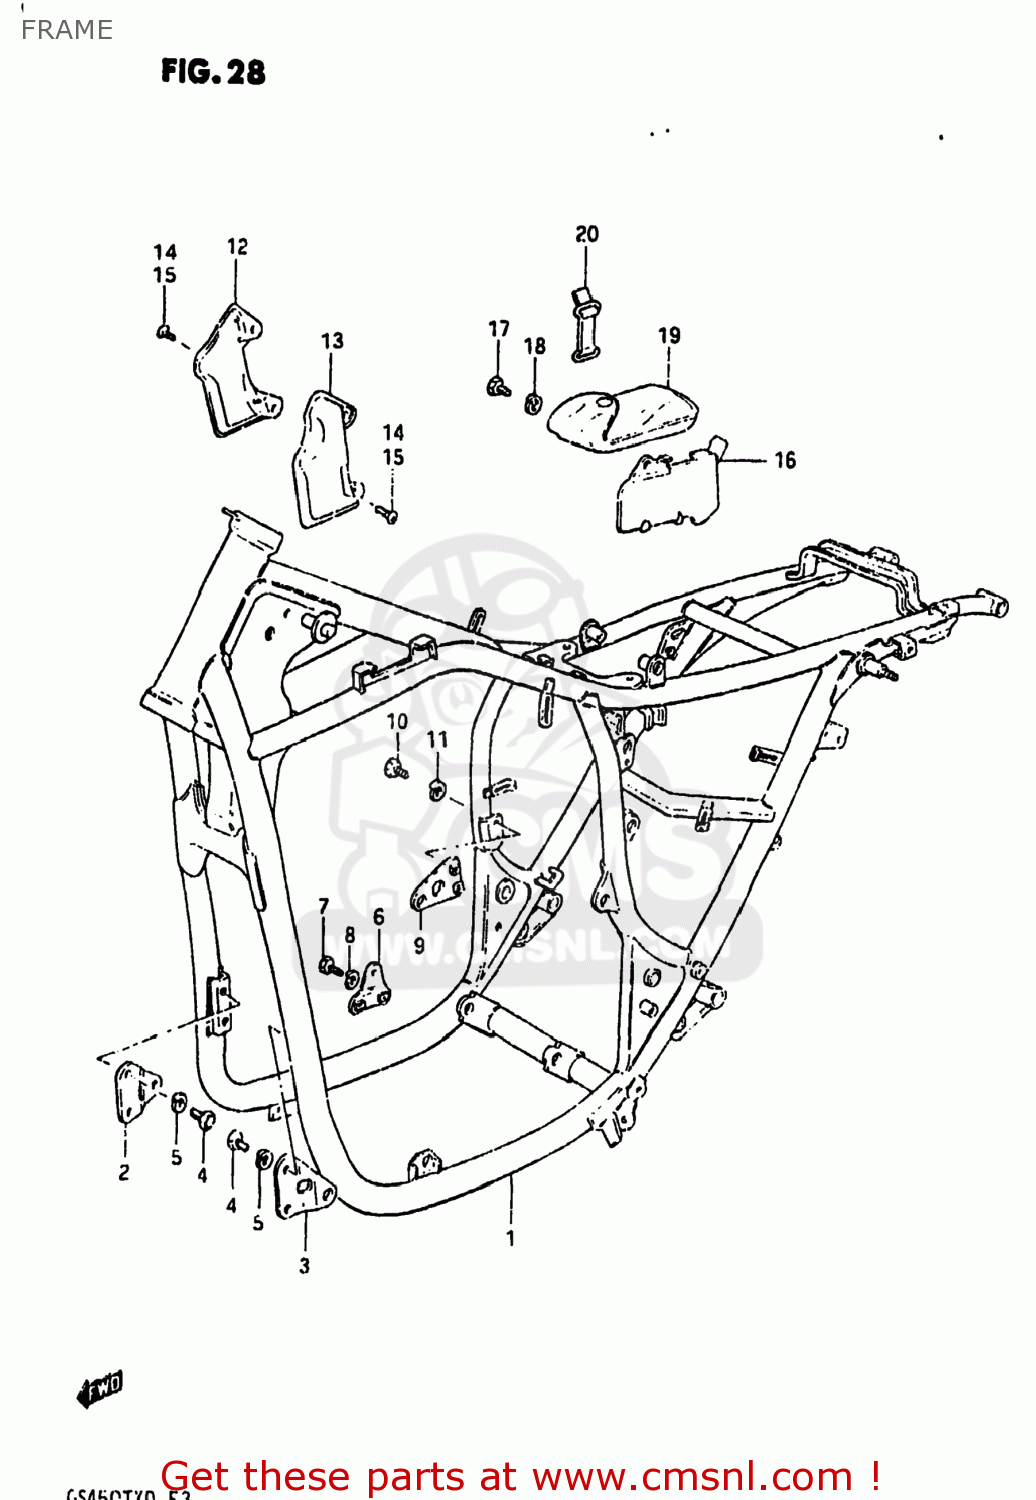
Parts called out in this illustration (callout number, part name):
1	FRAME
2	PLATE,ENG MTG NO.1,R
3	PLATE,ENGINE MOUNTING,LEFT
4	BOLT
5	LOCK WASHER
6	PLATE,MOUNTING NO.2,LEFT
7	BOLT
8	LOCK WASHER
9	PLATE,MOUNTING NO.4,LEFT
10	BOLT 8X45
11	LOCK WASHER
12	COVER,FRAME HEAD,RIGHT
13	COVER,FRAME HEAD,LEFT
14	(5X20) CROSS SCREW
15	SCREW, LOWER
16	HOLDER,TOOL
17	BOLT
18	LOCK WASHER
19	TOOL SET
20	BAND
